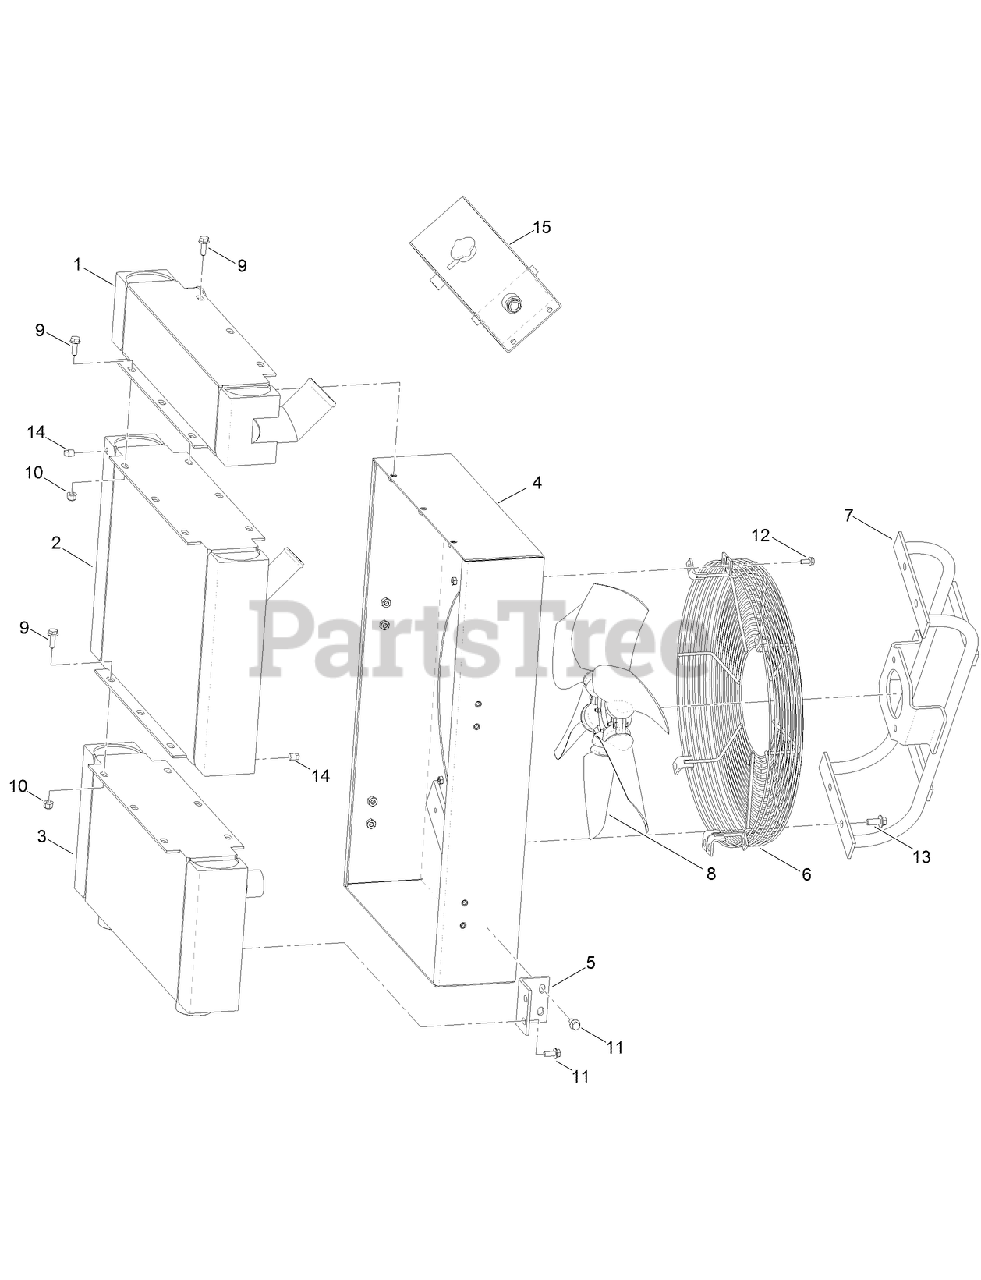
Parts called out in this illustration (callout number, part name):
1	COOLER-AIR, CHARGE
2	COOLER-RADIATOR
3	COOLER-OIL
4	SHROUD-FAN
5	PLATE-MOUNTING, SHROUD
6	GUARD-FAN, 22 INCH
7	BRACKET-MOUNTING
8	FAN-COOLING, 22 INCH
9	SCREW-HHF
10	NUT-LOCK, NI
11	SCREW-HHF
12	SCREW-HHF
13	SCREW-HHF
14	PLUG-PIPE, SQH
15	TANK-FILL/SURGE
